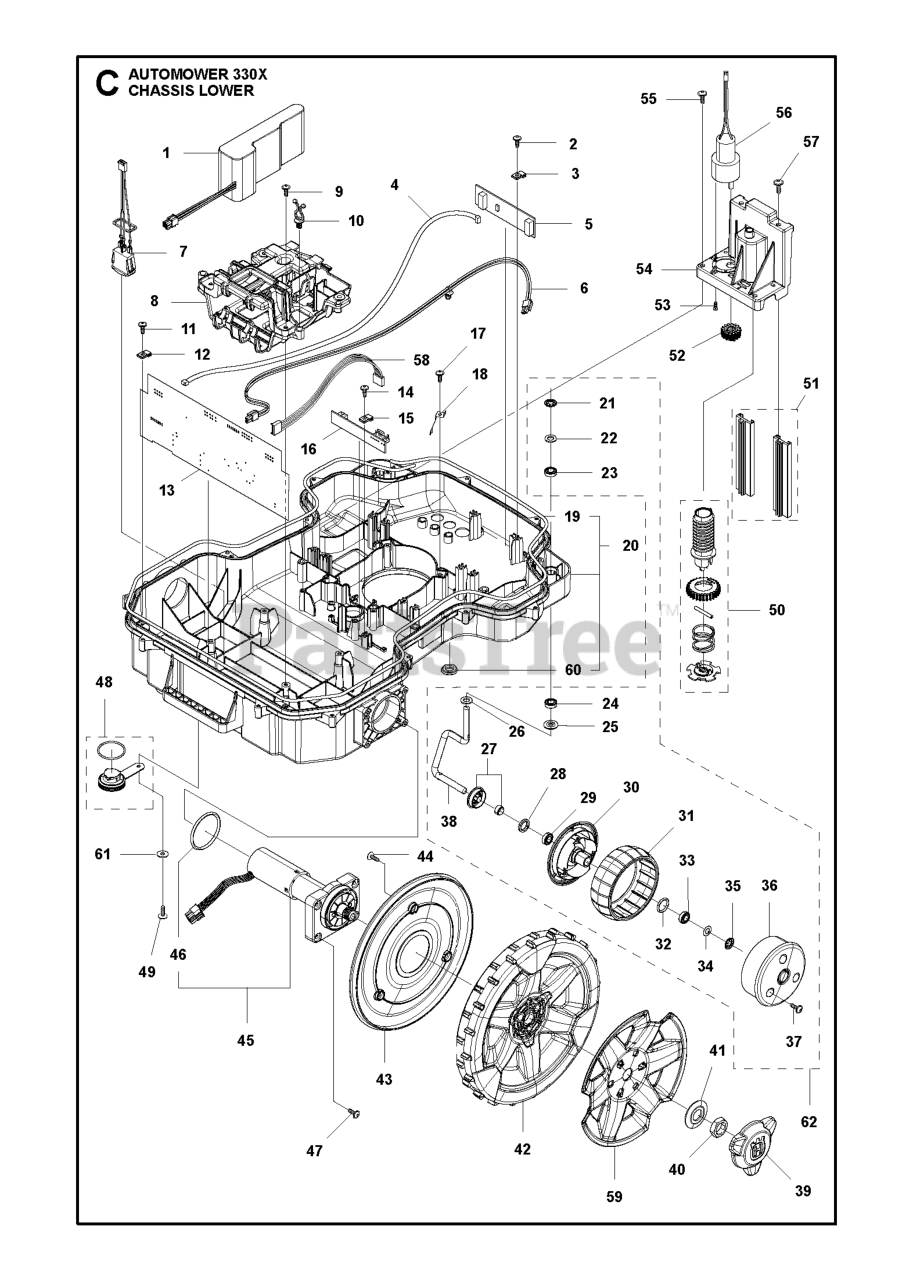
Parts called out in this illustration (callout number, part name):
1	BATTERY LI-ION
2	SCREW 14MM
4	LOOM LOOP SENSOR
5	PRINTED CIRCUIT ASSY PCBA LOOP
7	LOOM ON/ OFF
9	SCREW ITXPANT
10	HOLDER TWIST LOCK
11	SCREW 14MM
14	SCREW 14MM
17	SCREW 14MM
18	SPRING GUIDE HEIGHT ADJUSTMENT
19	SEALING STRIP
19	SEALING STRIP CHASSIS 10 PCS
21	LOCK WASHER PUSH-ON TYPE P 8 S
22	WASHER DIN 988 13X8X0.5
23	BALL BEARING SINGLE ROW S688
24	BALL BEARING SINGLE ROW S688
25	WASHER FRONT WHEEL CENTER HOLE
26	WASHER DIN 988 13X8X0.5
27	SHIELD KIT
28	SEALING 12X18X3
29	BALL BEARING SINGLE ROW S688
30	WHEEL FRONT WHEEL INSIDE
31	WHEEL RUBBER TYRE
32	O-RING 2,62X15,54
33	BALL BEARING SINGLE ROW S688
34	WASHER DIN 988 13X8X0.5
35	LOCK WASHER PUSH-ON TYPE P 8 S
36	WHEEL FRONT WHEEL OUTSIDE
37	SCREW 14MM
38	SPINDLE SPINDLE FRONT WHEEL RI
39	HUB CAP REAR WHEEL NO CENTER P
40	HEXAGON THIN NUT
41	WASHER WASHER REAR WHEEL 16X40
42	WHEEL ASSY D249 BLACK
43	COVER REAR WHEEL
44	SCREW 14MM
45	MOTOR KIT DRIVE WHEEL
47	SCREW ITXPANT
49	SCREW 14MM
51	BEARING KIT
55	SCREW 14MM
58	LOOM HEIGHT ADJUSTMENT
59	WHEEL COVER REAR WHEEL
62	WHEEL KIT FRONT
